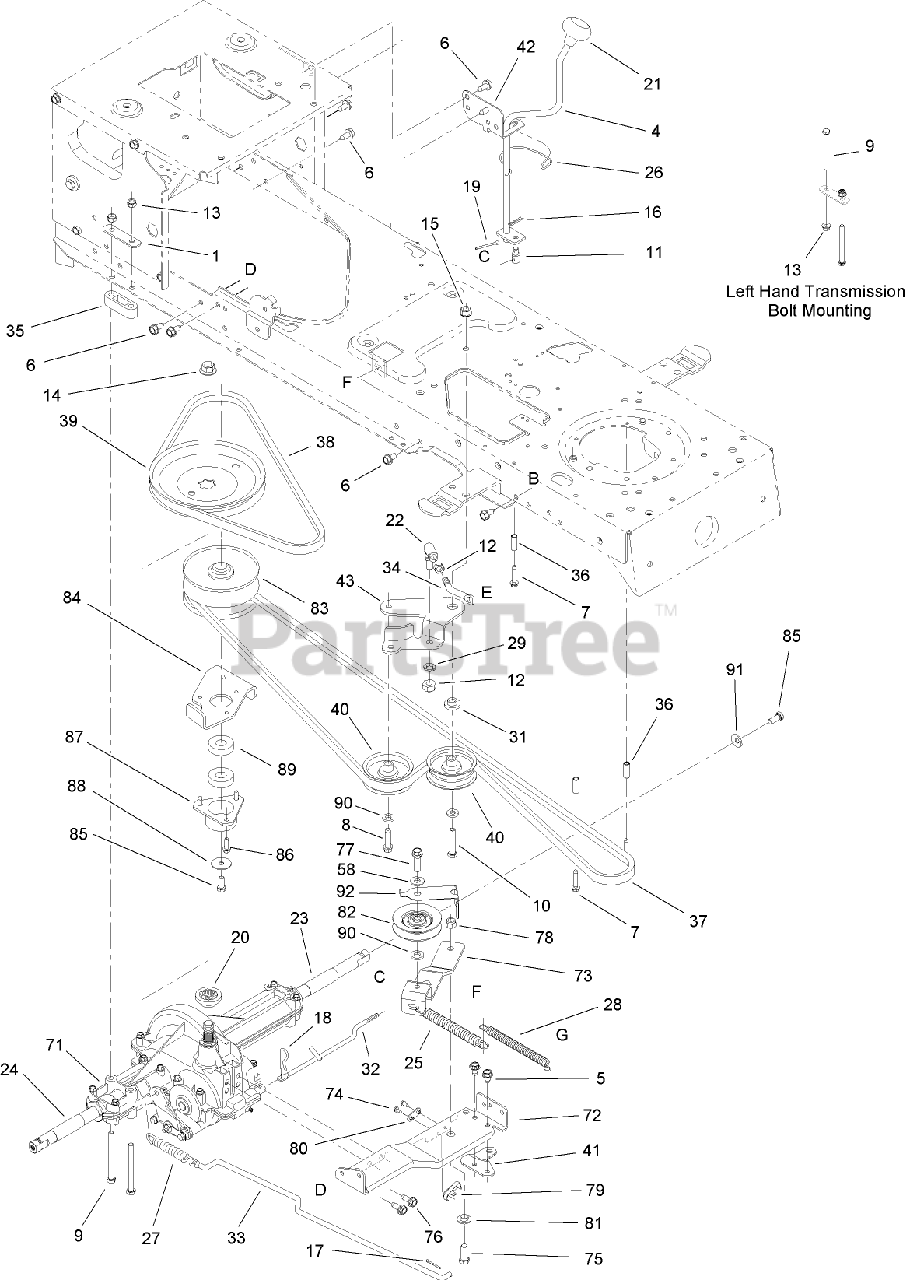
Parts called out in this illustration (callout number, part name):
1	BRACKET-MOUNTING, TRANSMISSION
4	SHIFT LEVER ASM
5	SCREW-TAP
6	SCREW-HH, TAP
7	SCREW-HH
8	SCREW-TAP
9	SCREW-HH
10	SCREW-HH
11	FERRULE-ADJUSTABLE
12	NUT-HEX
13	NUT-LOCK, FLANGE
14	NUT-FLANGE
15	NUT-LOCK, FLANGE
16	PIN-COTTER
17	PIN-COTTER
18	PIN-HAIR
19	PIN-COTTER
20	HUB-PULLEY
21	KNOB-SHIFT
22	BALL JOINT ASM
23	SLEEVE
24	SLEEVE
25	SPRING-EXTENSION
26	CLIP-SPRING, SHIFTER
27	SPRING-EXTENSION
28	SPRING-EXTENSION
29	WASHER-LOCK
31	SPACER-SHOULDER
32	ROD-SHIFT
33	ROD-BRAKE
34	ROD-ADJUSTMENT, IDLER
35	SPACER-TRANSAXLE
36	SPACER
37	BELT-DRIVE, VARIABLE SPEED
38	BELT-DRIVE, TRANSMISSION
39	PULLEY-V (W/HUB)
40	PULLEY-IDLER, FLAT
41	BRACKET-SHIFT
42	BRACKET-SHIFT
43	BRACKET-IDLER, CENTER DOUBLE
58	WASHER-FLAT
73	KIT - IDLER ARM
74	SCREW-HWHTF
75	SCREW-HH
76	SCREW-HWH
77	SCREW-TAP
78	NUT-LOCK, HEX
79	SWITCH-SPRING, SHORT
80	PLATE-INSULATOR
81	SPACER-SHOULDER
84	BRACKET-PULLEY
85	SCREW-HH
86	SCREW-TAP
87	CUP-BEARING
88	WASHER-FLAT
89	BEARING-BALL
90	WASHER-FLAT
91	WASHER-BELL
92	GUIDE-BELT, TRACTION
